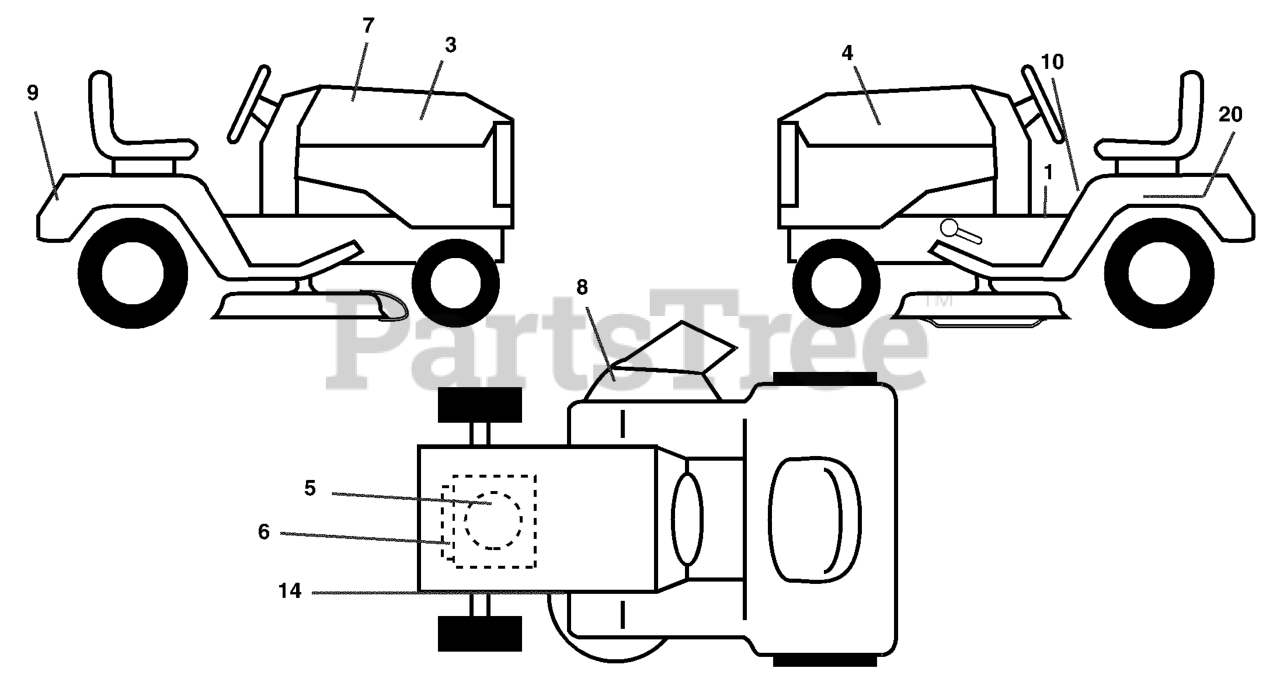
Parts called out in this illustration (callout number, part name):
1	DECAL FEND STLT OPER INST E/F
3	DECAL HOOD RH
4	DECAL HOOD LH
5	DECAL HOOD CUST. RESP.
6	DECAL ENGINE
7	DECAL REPLACEMENT
8	DECAL.WARN.KEEP.HAND.AWAY
9	DECAL, FENDER
10	DECAL FENDER DANGER
14	DECAL V-BELT SCHEMATIC
20	DECAL BTRY SYMBOLS
